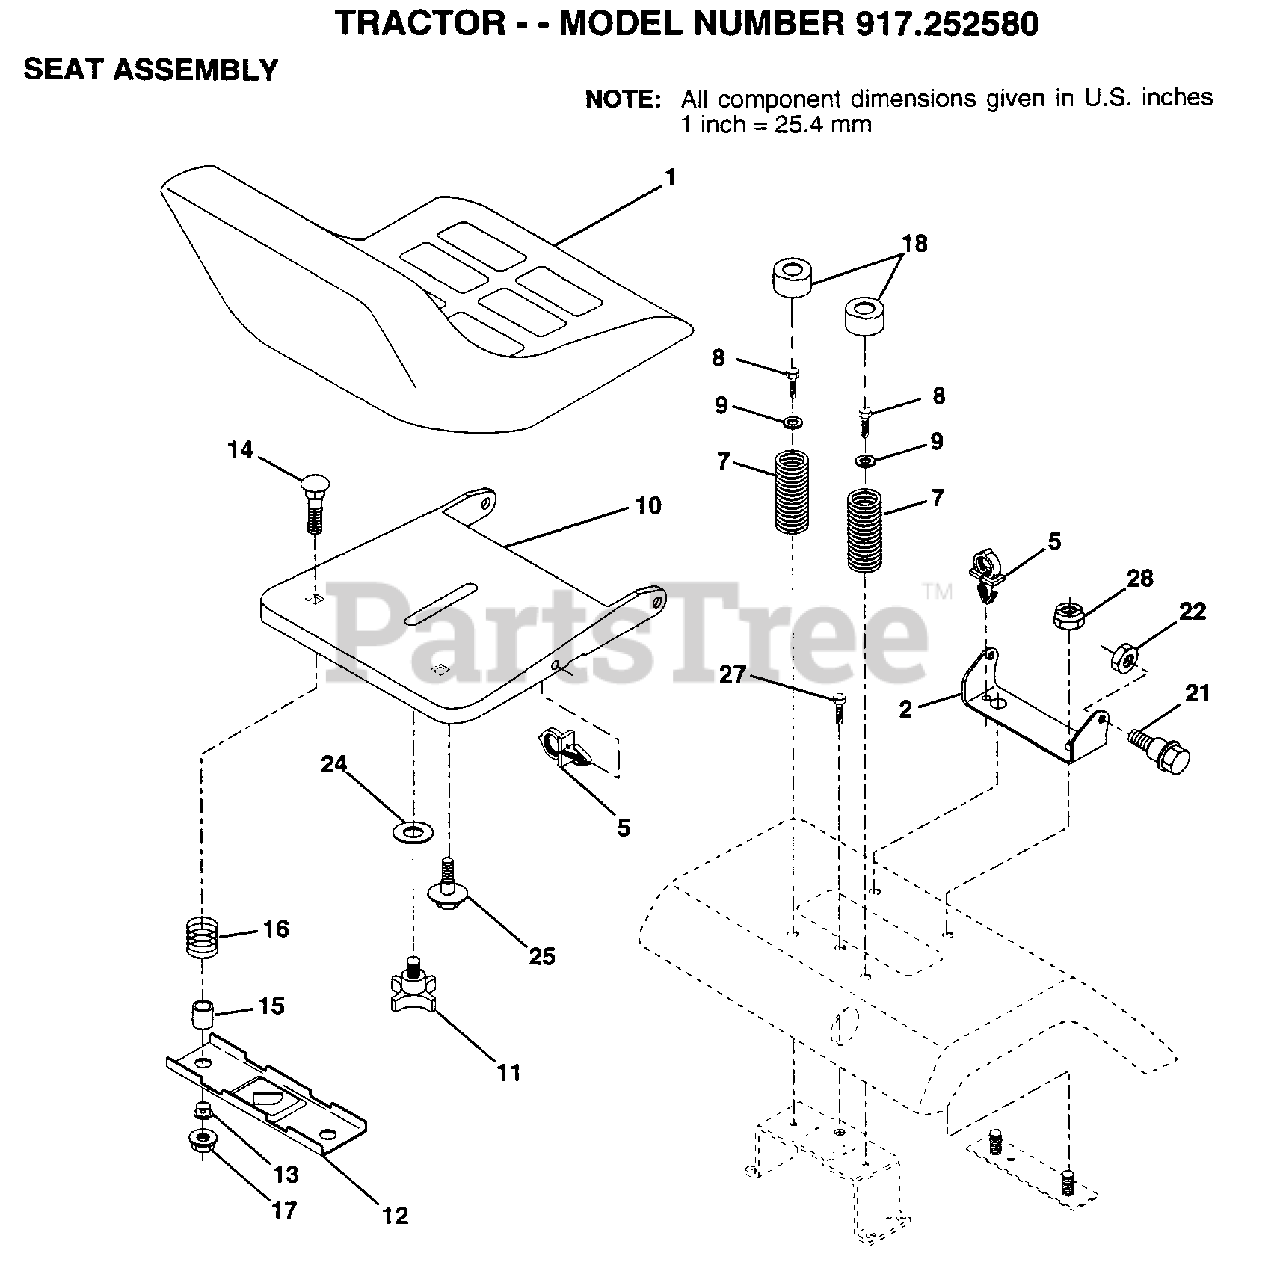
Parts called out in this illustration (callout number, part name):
2	BRACKET PVT SEAT
5	CLIP.PUSH-IN.HING
7	SPRING COMPRESSIO
8	SCREW LT
9	WASHER
11	"KNOB 1/2"" YT"
12	BRKT SWITCH
13	BUSHING
15	SPLIT SPACER
16	SPRING
18	CAP SPRING
21	BOLT.SHLD.5/16-18
24	WASHER
25	"BOLT,SHOULDER"
27	SCREW LT
